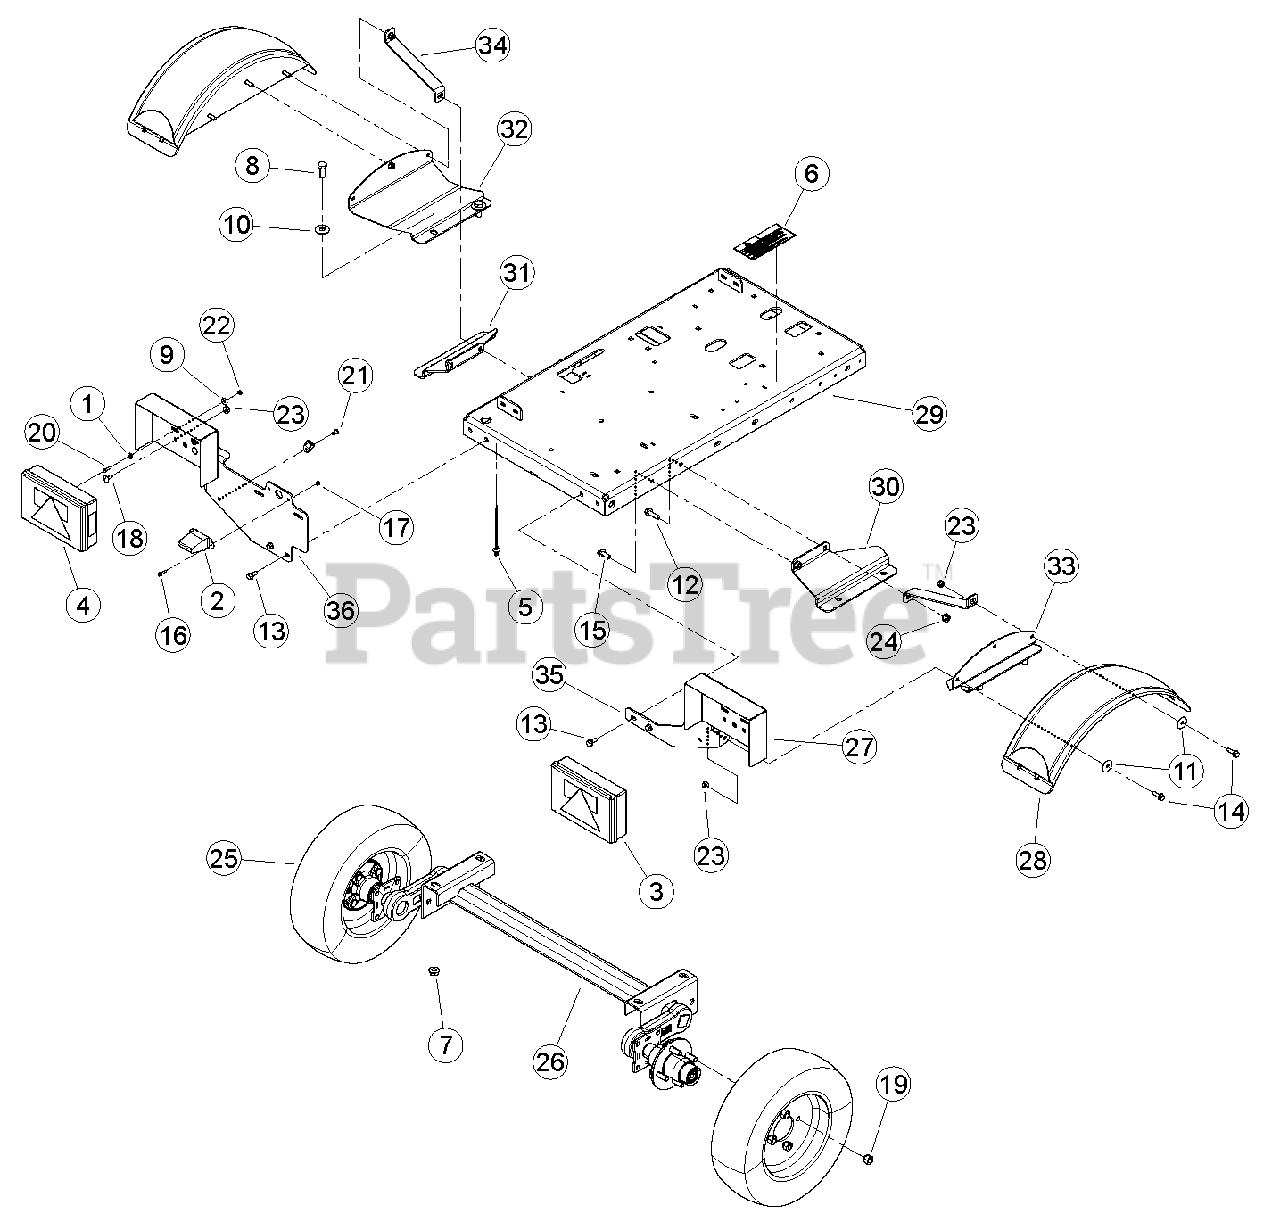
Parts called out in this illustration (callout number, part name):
1	GROMMET, 1/4 X 5/8 RUBBER
2	LIGHT, LICENSE PLATE
3	LIGHT, TAIL RH
4	LIGHT, TAIL LH
5	TIE, DOME FIR TREE
6	DECAL, MUTILINGUAL MANUAL
7	NUT, 1/2" SERRATED FLANGE
8	BOLT, 1/2 X 1-1/4" GR5 HHCS NC ZP
9	WASHER, 1/4" FLAT ZP
10	WASHER, 1/2" FLAT Z
11	WASHER, 5/16" FENDER ZP-32PCS/LB
12	BOLT, 3/8 X 1-1/4 FLANGE NC
13	BOLT, 5/16 X 3/4 FLANGE NC
14	BOLT, 5/16 X 1 FLANGE NC
15	BOLT, 3/8 X 1 FLANGE NC
16	SCREW, #10 X 3/4 HEX TAP SC
17	NUT, 8-32 NYLOCK
18	BOLT, 5/16X3/4 GR5 NC ZP CRG
19	NUT, 1/2-20 WHEEL
20	BOLT, 10-24 X 3/4" HHCS GR8 PLAIN
21	RIVET, AL BLIND 1/4 X 3/4 DOME HEAD
22	NUT, #10-24 K-LOCK ZP
23	NUT, 5/16-18 NYLOCK-FLANGE
24	NUT, 3/8-16 NYLOCK-FLANGE
25	ASSEMBLY, TIRE + WHEEL 4.80-8
26	AXLE, 1000LB TORSION
27	BRACKET, LIGHT
28	FENDER, BLACK PLASTIC DRILLED
29	WELDMENT, CHIPPER TRAILER
30	SUPPORT, AXLE FENDER RH
31	SUPPORT, AXLE FENDER LH
32	SHEET, MOUNT FENDER LH
33	SHEET, MOUNT FENDER RH
34	BRACKET, FENDER SUPPORT
35	BRACKET, LIGHT RH
36	BRACKET, LIGHT LH
